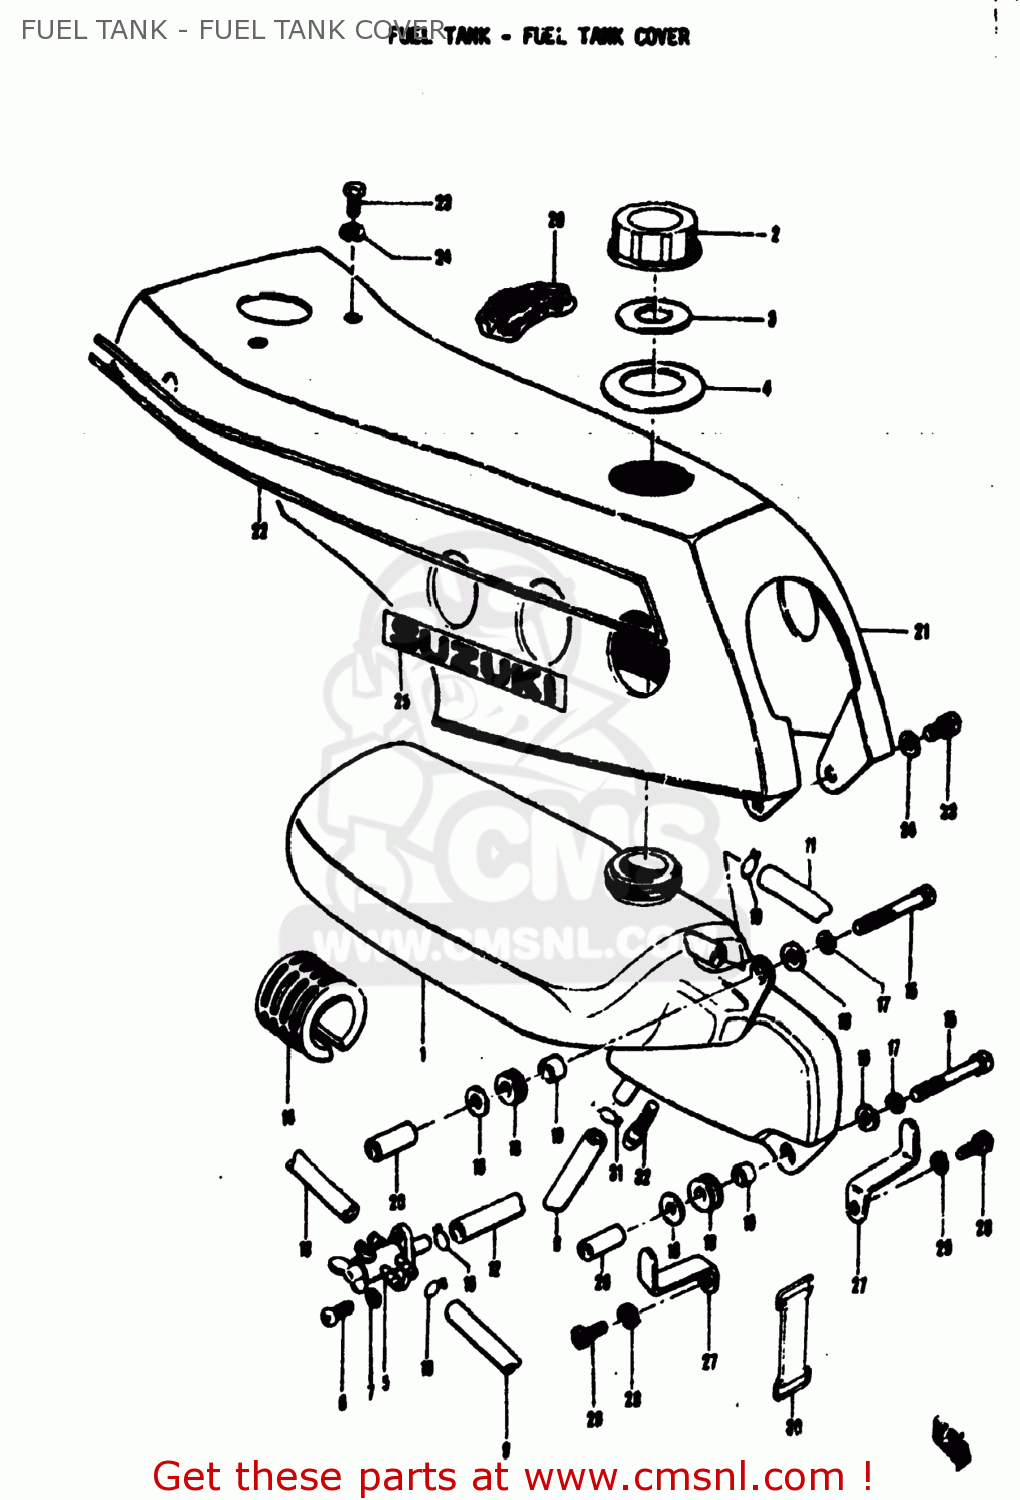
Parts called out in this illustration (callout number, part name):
2	CAP,FUEL TANK
3	GASKET
4	RUBBER,FUEL TANK INLET
6	SCREW
7	LOCK WASHER
8	HOSE
9	HOSE
10	CLIP
11	HOSE
12	HOSE
13	HOSE
14	CUSHION,FUEL TANK
15	BOLT
16	WASHER
17	LOCK WASHER
18	CUSHION
19	SPACER (6.8X10X10)
20	SPACER (6.8X10X27.4)
22	TAPE,FUEL TANK
23	SCREW(6X14)
24	WASHER
25	EMBLEM,SUB FUEL TANK
28	SCREW(6X14)
29	LOCK WASHER
30	BAND
31	CLIP
32	FILTER,FUEL
